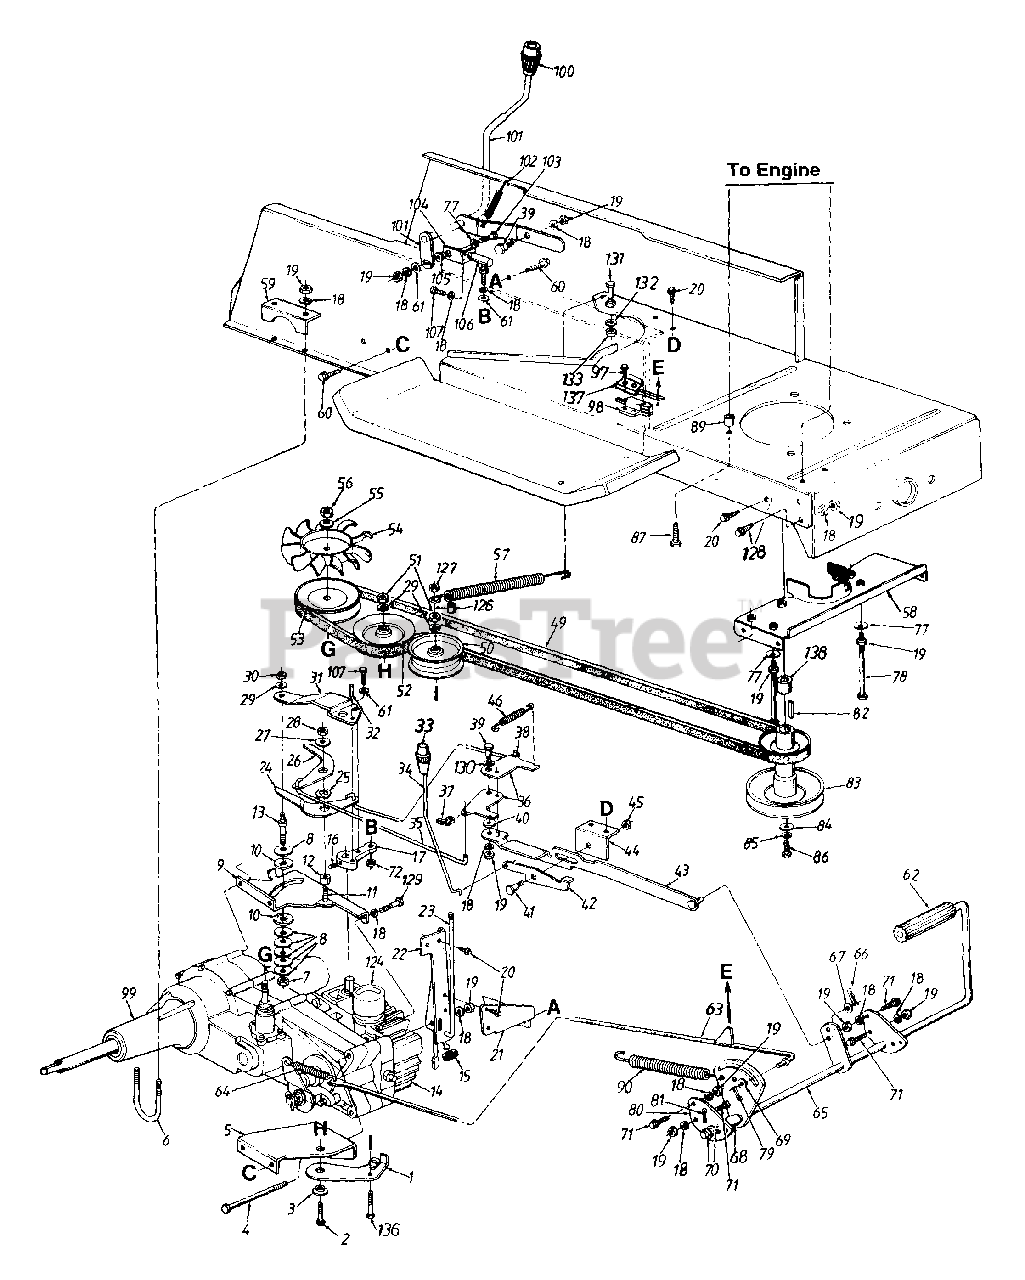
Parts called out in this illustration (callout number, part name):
1	Idler Bracket
2	Hex Bolt 3/8-16 x 2.0" Lg.
3	Shld. Spacer .625" I.D.
4	Hex Bolt 5/16-18 x 4.5" Lg. (Gr. 5)
5	Idler Plate
6	U-Bolt 5/16-18 x 1.75" Lg.
7	Hex L-Nut 3/8-24 Thd.
8	Bell-Wash..40" I.D. x 1.13"
9	Mounting Bracket
10	Friction Washer
11	Rib Neck Bolt 5/16-24 x .84" Lg.
12	Spacer
14	Hydrostatic Pump
15	Rubber Washer .33" I.D.
16	Set Screw
17	Pintle Shift Lever
18	L-Wash. 5/16" I.D.
19	Hex Nut 5/16-18 Thd.
20	Hex TT-Tap Scr. 1/4-20 x .5"
21	Reinforcement Plate
22	Transmission Torque Brkt.
23	Release Valve Rod
24	Reverse Arm
25	Spring Washer .625" I.D.
26	Forward Arm
27	Fl-Wash..344" I.D. x 1.0"
28	Hex Cent. L-Nut 5/16-24 Thd.
29	L-Wash. 3/8" I.D.
30	Hex Nut 3/8-24 Thd.
31	Pintle Arm Ext. Plate
32	Roll Pin 1/4" Dia. x .75" Lg.
33	Knob
34	Lock-Up Rod
35	Connection Rod
36	Balancer Bracket
37	Rod End Clevis Clips - R.H.
38	Rod End Clevis Clips - L.H.
39	Shld. Bolt .437" Dia. x .268"
40	Fl-Wash..344" I.D. x 1.12"
41	Shld. Bolt .437" Dia. x .35"
42	Lock-Up Bracket
43	Neutral Return Brkt. Ass'y.
44	Bracket
45	Hex Cent. L-Nut 5/16-18 Thd.
46	Ext. Spring 2.5" Lg.
49	"V"-Belt
51	Hex Nut 3/8-16 Thd.
52	idler Pulley 4.0" O.D.
53	Transmission Pulley
54	Hydro Fan
55	Bell-Wash..56" I.D. x 1.125"
56	Hex Jam Nut 9/16-18 Thd.
57	Extension Spring
58	Belt Guard Brkt. Ass'y.
59	Bracket
60	Hex B-Tap Scr. 5/16-18 x .5"
61	Flat Tooth Washer 5/16" I.D.
62	Foot Pad
63	Brake Rod Ass'y.
64	Ext. Spring 3.67" Lg,
65	Clutch Brake Pedal Ass'y.
66	Cotter Pin 1/8" Dia.
67	Fl-Wash..385" I.D. x .62"
68	Spacer .63" I.D.
69	Fl-Wash..385" I.D. x .62"
70	Fl-Wash..635" I.D. x 1.0"
71	Hex TT-Tap Scr. 5/16-18 x 7/8"
72	Hex Nut 5/16-24 Thd.
77	Bell-Wash..345" I.D. x .88"
78	Hex Bolt 5/16-18 x 4.0" Lg.
79	Cotter 3/32" Dia. x .75" Lg.
82	Sq.-Key 1/4" x 2.0"
83	Engine Pulley
84	Fl-Wash. 7/16" I.D. x 1.25"
85	L-Wash. 7/16" I.D. (H.D.)
86	hex Bolt 7/16-20 x 1.5" Lg.
87	Hex L-Wash. TT-Tap Scr. 3/8-16 Thd.
89	Spacer 5/16" I.D.
90	Extension Spring 6.11" Lg.
97	Truss Mach. B-Tap Scr. #10 x .5" Lg.
98	Safety Switch (Clutch)
99	Transaxle
100	Shift Knob
101	Speed Selector Lever Ass'y.
102	Ext. Spring 2.75" Lg.
103	Hex Holt 5/16-18 x 1.25" Lg.
104	Connection Brkt.
105	Shoulder Nut
106	Ball Joint 5/16-24 Thd.
107	Hex Bolt 5/16-24 x .75" Lg.
124	Reservoir
126	Spacer .375" I.D. x .503
127	Hex Jam Nut 3/8-16 Thd.
128	I-lex Wash. TT-Tap Scr. 5/16-18 x .62" Lg.
129	Hex Bolt 5/16-18 x 4.75" Lg.
130	Spr.-Wash..445" I.D. x .75" O.D
131	Hex Bolt 1/4-20 x 1.25" Lg.
132	L-Wash. 1/4" I.D.
133	Hex Nut 1/4-20 Thd.
136	Hex Bolt 3/8-16 x 2.5" Lg.
137	Switch Plate
138	Engine Pulley Spacer
